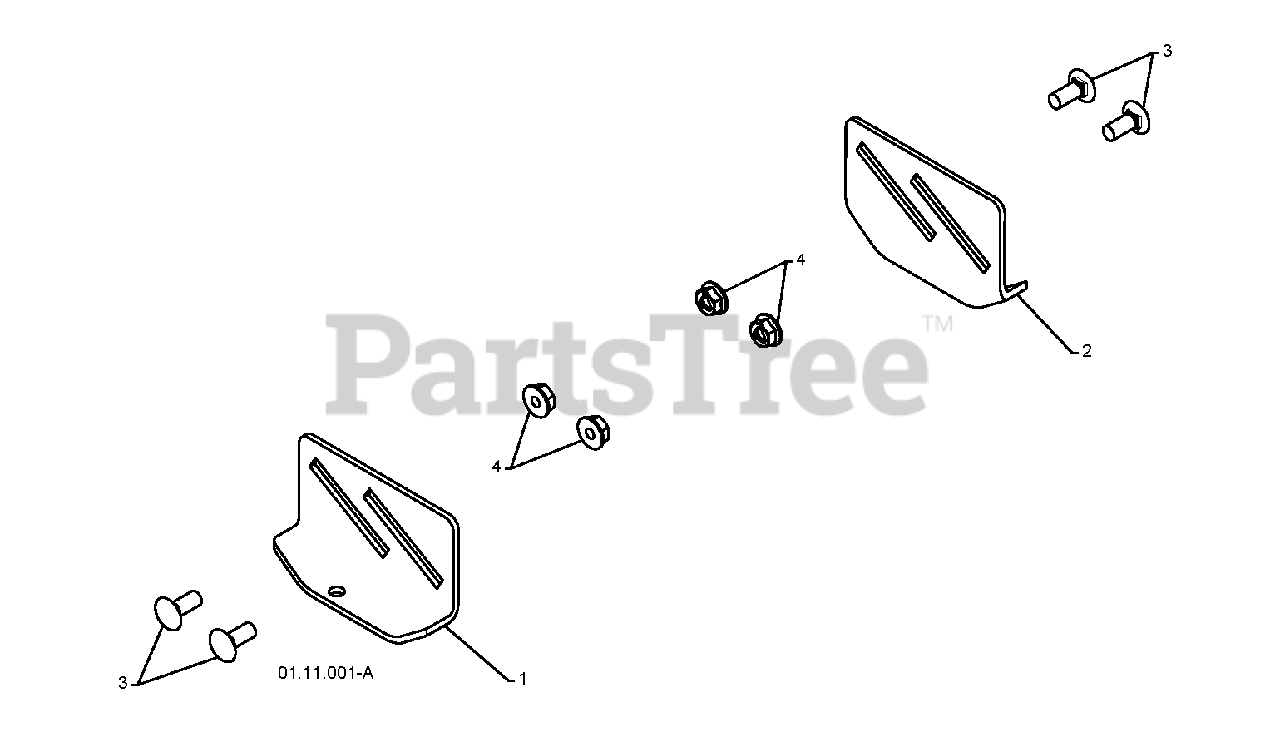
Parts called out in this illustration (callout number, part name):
1	SKID PLATE LH
2	SKID PLATE RH
4	NUT, LOCK 5/16-18
